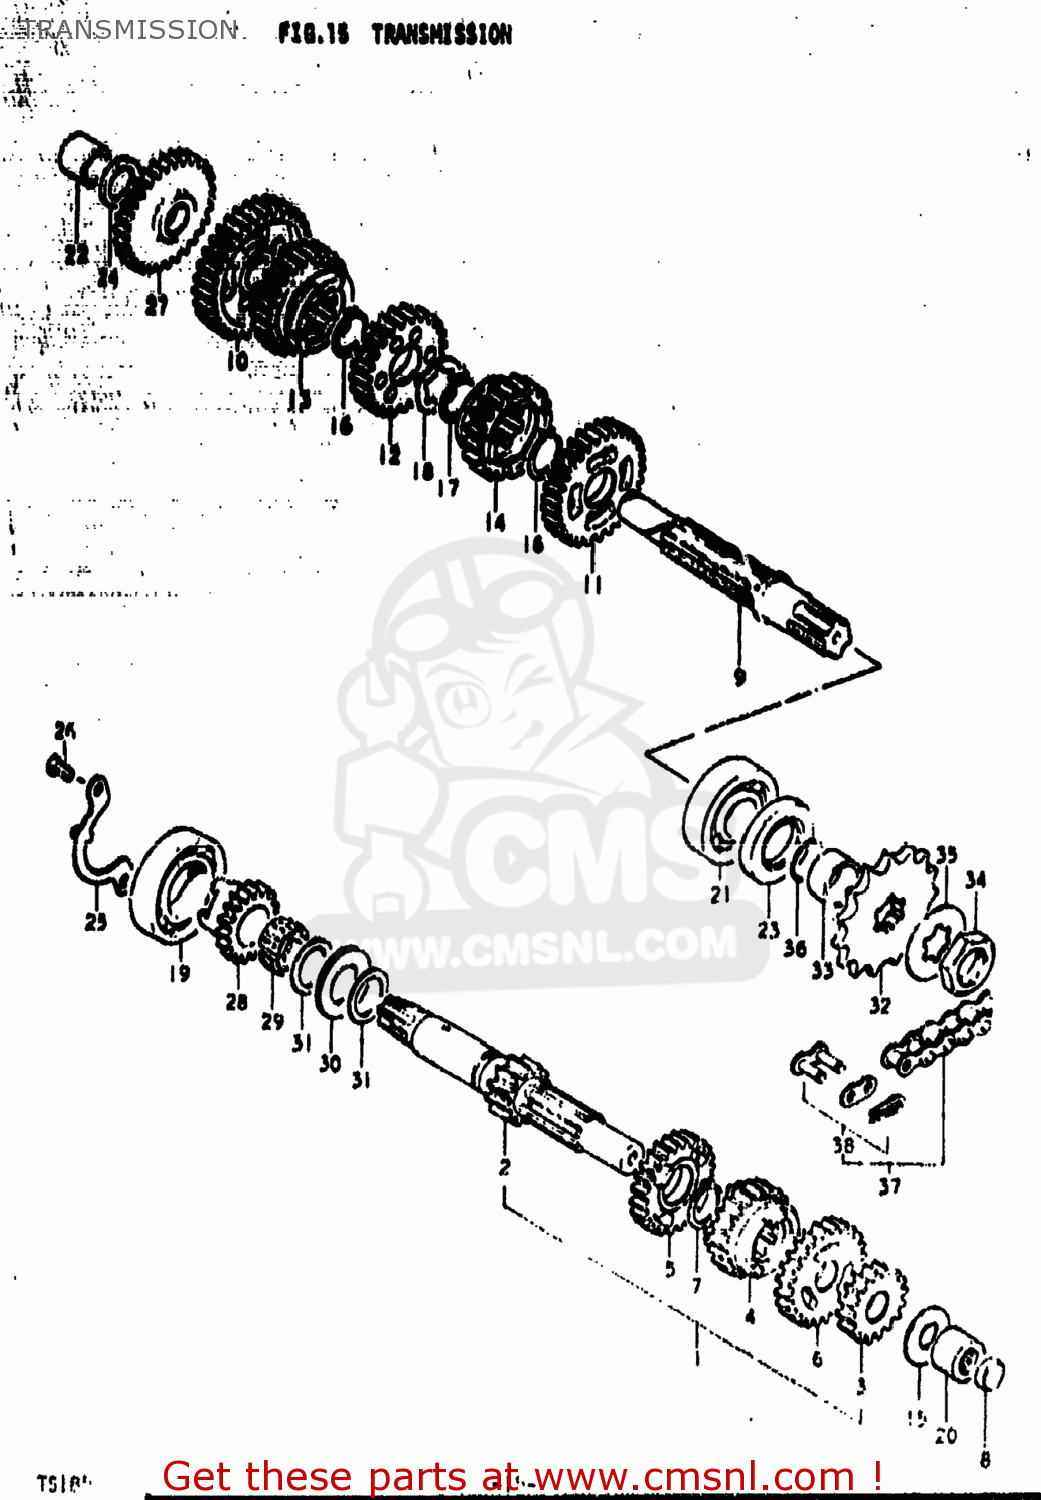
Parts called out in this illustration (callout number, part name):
1	SHAFT,COUNTER
2	SHAFT,COUNTER
3	GEAR,2ND DRIVE
4	GEAR,THIRD DRIVE
5	GEAR,FOURTH DRIVE
6	GEAR,FIFTH DRIVE
7	CIRCLIP
8	PLUG
9	SHAFT,DRIVE
10	GEAR,1ST DRIVEN
11	GEAR,SECOND DRIVEN
12	GEAR,THIRD DRIVEN
13	GEAR,FOURTH DRIVEN
14	GEAR,FIFTH DRIVEN
15	WASHER
16	CIRCLIP
17	CIRCLIP
18	WASHER
19	BEARING, RH
20	BEARING(15X22X15)
21	BEARING
22	BUSH
23	OIL SEAL (25X44X7)
24	WASHER
25	RETAINER,CNTR SHAFT BEARING
26	SCREW
27	GEAR,KICK STARTER IDLE
28	GEAR,KICK STARTER DRIVE
29	BEARING(19.2X23.2X19)
30	BEARING 21X35X2.8
31	WASHER(21X30X0.8)
32	SPROCKET,ENGINE
33	SPACER(20X25X12.5)
34	NUT
35	WASHER,LOCK
36	O RING(D:1,ID:19.5)
37	CHAIN ASSEMBLY,DRIVE
38	JOINT ASSEMBLY,CHAIN
